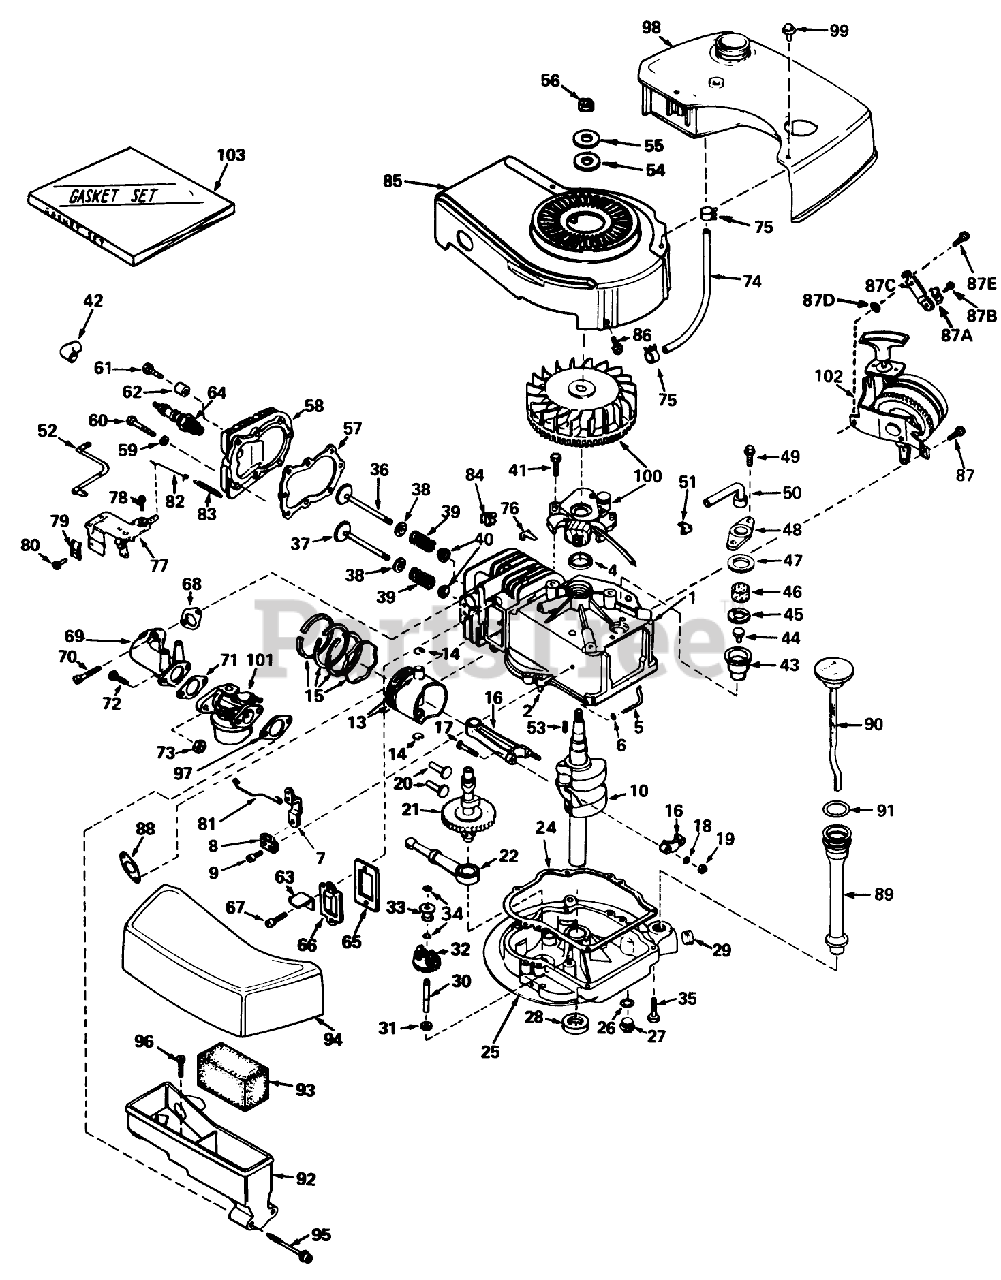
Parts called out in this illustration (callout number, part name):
1	Cylinder Assy. (Incl. Ref. #2, 4 105)
2	Pin-Dowel
4	OIL SEAL
5	Rod, Governor (Incl. No. 36)
6	Washer-Flat
7	Governor Lever
8	Clamp-Lever, Governor
9	Screw
10	Crankshaft Assembly (Incl. Nos. 12 13)
13	Piston Pin Assembly (Incl. 2 of No. 14) (.010 Oversize)
13	Piston Pin Assembly (Incl. 2 of No. 14) (.020 Oversize)
14	Ring-Retaining, Piston Pin
15	Ring Set Piston (Std.)
15	Ring Set Piston (.010 Oversize)
15	Ring Set Piston (.020 Oversize)
16	Rod Assy., Connecting (Incl. Ref. #17)
17	Bolt, Connecting
18	Washer
19	LOCKNUT
20	Lifter-Valve
21	Camshaft (Compression Release
22	Oil Pump ASM
24	Gasket, Mounting
25	Filter, Air Cleaner
26	Gasket-Oil Drain
27	Plug Oil Drain
28	Seal Oil
29	Plug Oil Drain
30	Shaft-Governor
31	Washer-Flat
32	Governor Gear ASM
33	Spool-Governor
34	Ring-Retaining
35	Screw (1/4-20 x 1-1/4)
36	Valve, Intake (Incl. Ref. #38, 39 40) (Std.)
36	Valve, Exhaust (1/32" Oversize) (Incl. Nos. 8, 9 10)
37	Valve, Exhaust (Standard) (Incl. Nos. 8, 9 10)
37	Valve, Exhaust (1/32" Oversize) (Incl. Nos. 8, 9 10)
38	Cap-Upper Valve Spring
39	Spring-Valve
40	Cap-Valve, Spring
41	Screw
42	Cover-Spark Plug
43	Body Breather Tube
44	Valve Check
45	2000A37 WIZARD ROTA
46	Element-Breather
47	Gasket-Breather
48	Cover Breather
49	Screw, Hex Hd. w/Conical
50	Tube, Breaker
51	Clip, Breather
52	Wire, Ground
53	Key Flywheel
54	Washer Flat
55	Washer-Spring
56	Hex Nut
57	63573 GIL 42 SNWTHW
58	Head Cylinder
59	Washer
60	Screw
61	Screw Hex Hd. Cap
62	Space
63	Retainer Clip
64	Plug, Spark (J17LM or equiv.)
65	Gasket-Breather
66	Cover-Valve
67	Screw
68	Gasket, Intake
69	Pipe, Intake
70	Screw (1/4-20 x 1)
71	Gasket-Carburetor
73	Nut and Lock Washer (1/4-28)
74	Line-Fuel
75	Clamp-Line, Fuel
76	Clip-Wire
77	Control Assy., Speed
78	Screw (10-24 x 3/4)
79	Conduit
80	Screw (10-32 x 3/8)
81	Link Governor
82	Link Governor Spring
83	Spring Governor
84	51004 GIL ROTARY TI
85	Housing, Blower
86	Screw
87	Screw (1/4-20 x 1/2)
87A	Conduit
87B	Screw (10-32 x 3/8)
87C	Bracker
87D	Washer
87E	Screw (1/4-20 X 5/8)
88	Gasket Exhaust
89	Tube, Oil Filler
90	Dipstick, OiI (Incl. No. 91)
91	O-Ring
92	Body Air Cleaner
93	Filer, Air
94	Cove, Air Cleaner
95	Screw Fil Hd.
96	Screw, Hex Hd.
97	Gasket-Air Cleaner
98	Tank Fuel
99	Screw (10-32 x 35/64)
100	Magneto
101	Carburetor (Incl. No. 71)
102	Starter
103	53024/VAR.16HP O/P
